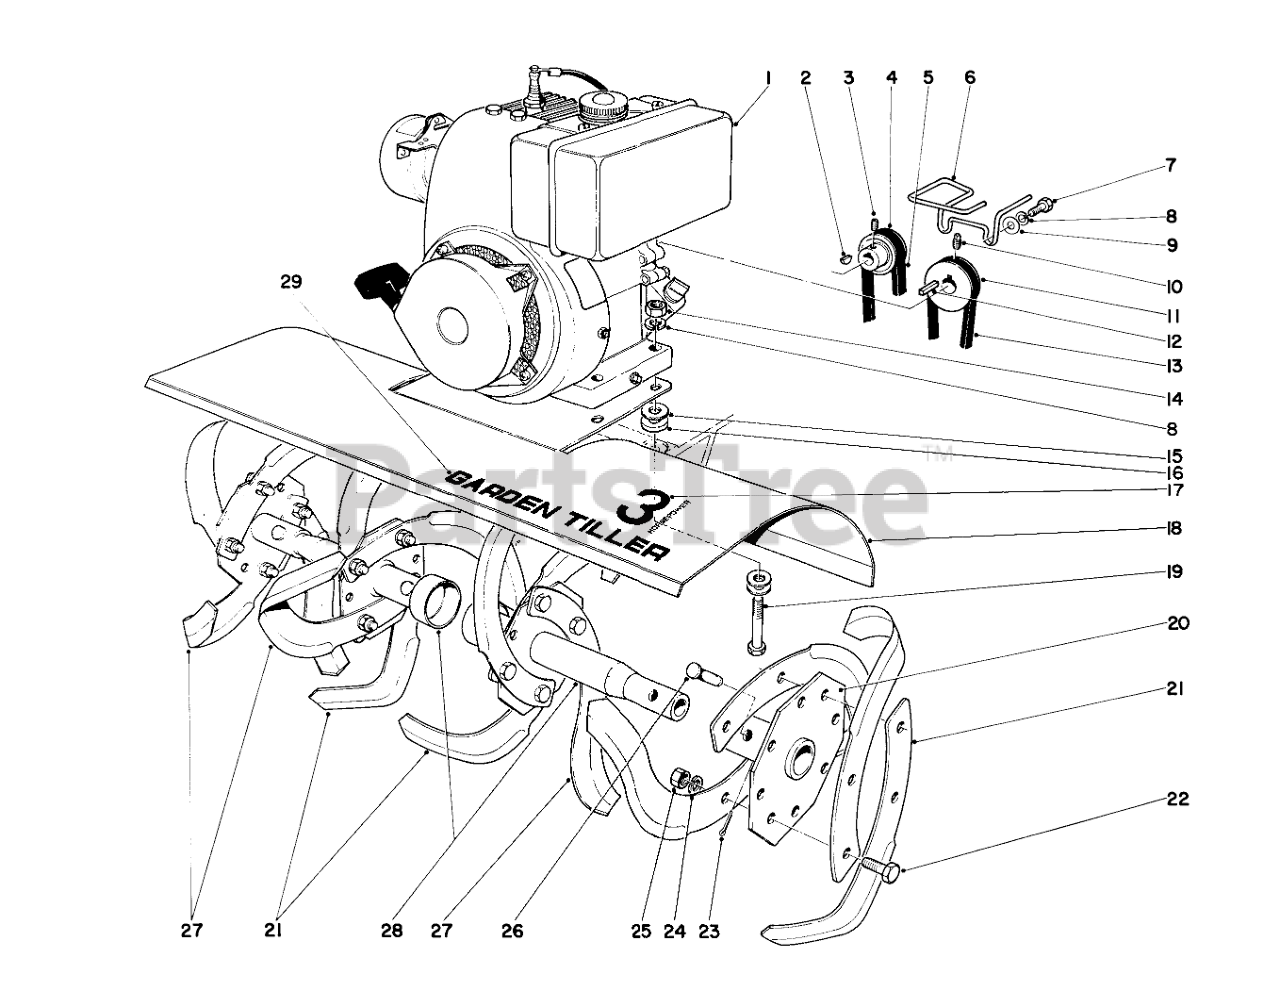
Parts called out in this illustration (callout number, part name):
1	Engine
2	KEY-WOODRUFF
3	SCREW-SET
4	Pulley
5	V-BELT
6	Belt Guide
7	SCREW-HH
8	WASHER-LOCK
9	WASHER-FLAT
10	SCREW-SET, HSH
11	Engine Pulley
12	KEY-SQUARE
14	NUT-HEX
15	WASHER-FLAT
16	WASHER-FLAT
17	Decal "3 HP"
18	Shield
19	SCREW-HH
20	Axle Hub
21	RH TINE
22	SCREW-HH
23	PIN-COTTER
24	WASHER-LOCK
25	NUT-HEX
26	PIN-CLEVIS
27	LH TINE
28	Axle Hub
29	Decal
